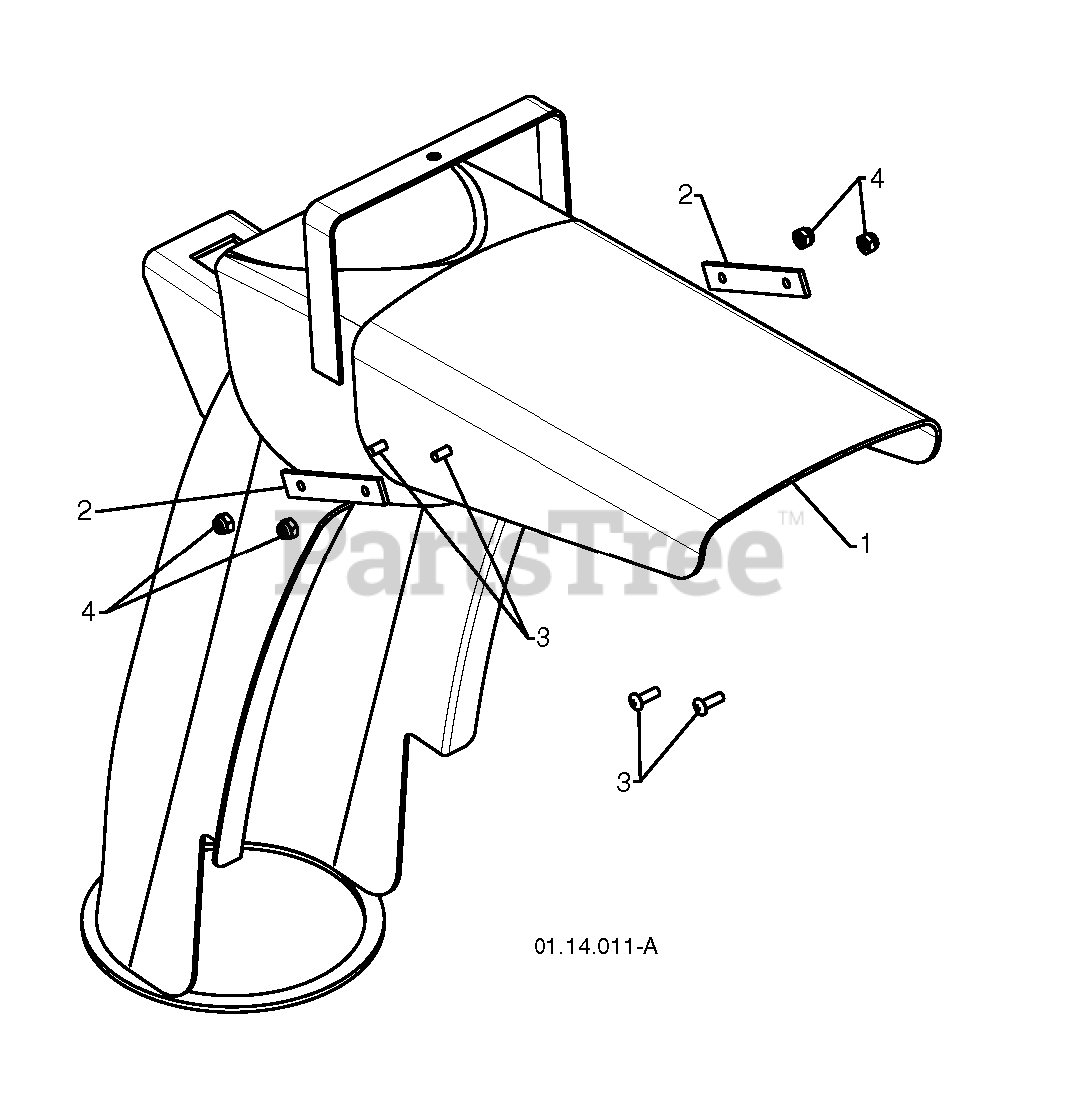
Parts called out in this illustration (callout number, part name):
1	SHIELD.DEFLECTOR.BLACK.SNOW
2	STRAP.DEFLECTOR.SHEILD
3	SCREW.#8.MACH
4	NUT.HEX.#8
